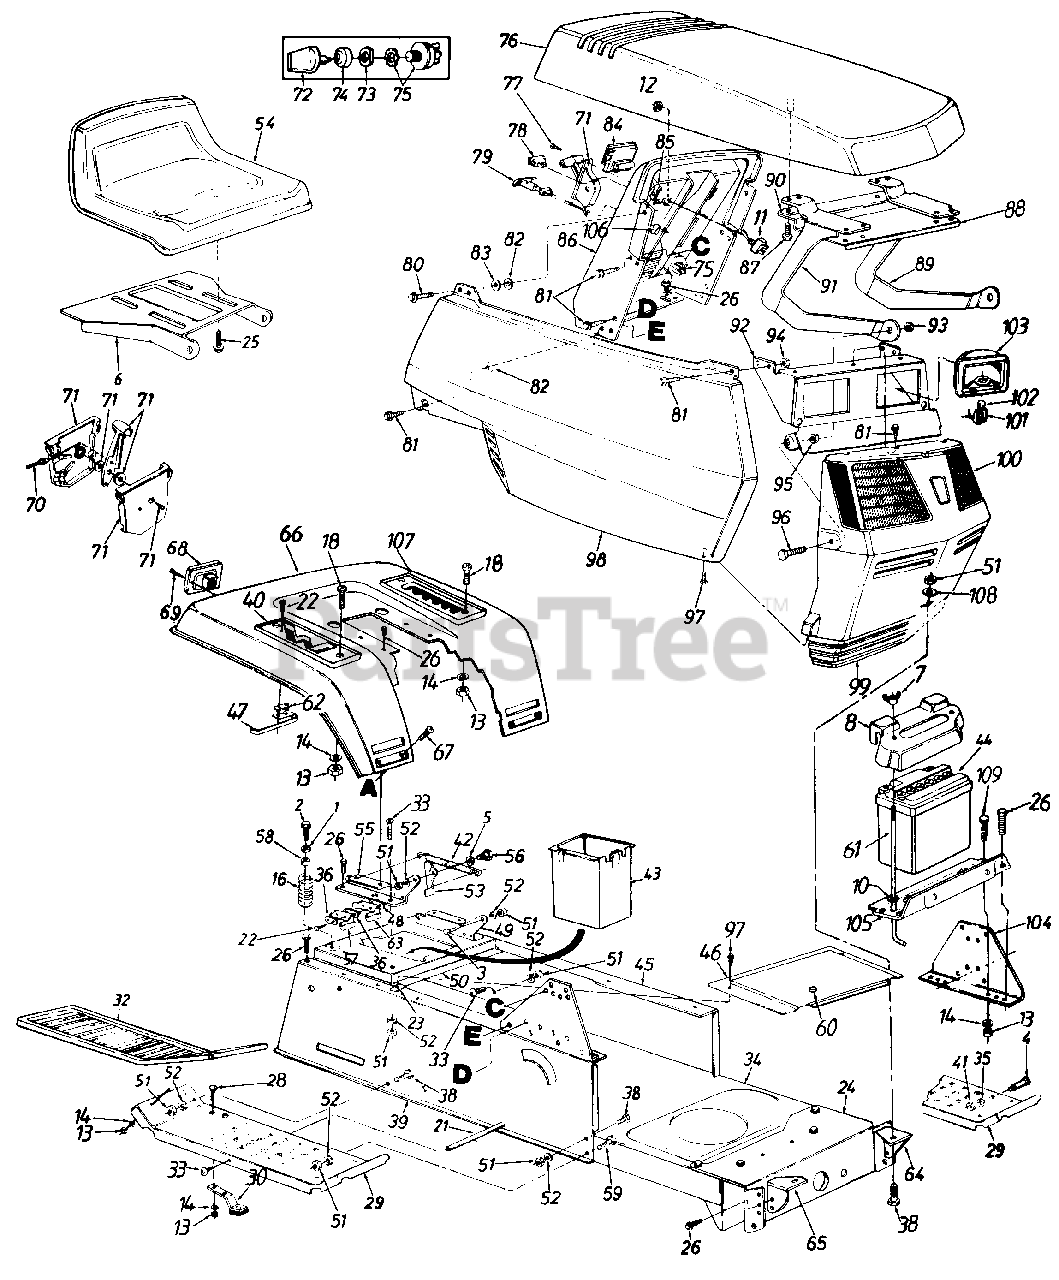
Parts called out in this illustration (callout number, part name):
1	Fl-Wash. .344" I.D. x .875"
2	Hex Wash. Hd. Tap Scr. 5/16-18 x 1.25" Lg.
3	Shld. Bolt .437" Dia. x .162"
4	Shld. Bolt .50" Dia. x .84"
5	Spr-Wash. .445" I.D. x .75
6	Seat Pivot Bracket
7	Wing Nut 1/4-20 Thd.
8	Battery Cover
10	Push Nut
11	Toggle Switch
12	Hex Nut l/2-27 Thd.
13	Hex Nut 1/4-20 Thd.
14	L-Wash. 1/4" I.D.
16	Compression Spring
18	Truss Mach. Scr. 1/4-20 x .75" Lg.
21	Running Board Rod
22	Hex Wash. Hd. AB-Tap Scr. #8 x .50" Lg.
23	Speed Nut #10Z
24	Front Pivot Brkt.
25	Hex Tap Scr. 3/8-16 x .75"
26	Hex Wash. Hd. AB-Tap Scr. 5/16 x .75" Lg.
28	Carriage Bolt 1/4-20 x .62"
29	Running Board
30	Blade Brake Ass'y.
32	Rubber Foot Pad L.H.
33	Truss Mach. Scr. 5/16-18 x .75" Lg.
34	Lower Frame
35	L-Wash. 3/8" I.D.
36	Insulator Plate
38	Hex Bolt 5/16-18 x .75" Lg.
39	Upper Frame R.H.
40	Forward/Reverse Index Brkt.
41	Hex Nut 3/8-16 Thd.
42	Extension Spring 5.31" Lg.
43	Utility Box
44	12-V Battery (275 Cold Crank Amps)
45	Upper Frame L.H.
46	Shift Cover
47	Reverse Safety Switch
48	Insulator Boss Plate
51	Hex Nut 5/16-18 Thd.
52	L-Wash. 5/16" I.D.
53	Seat Lift Brkt.
54	Seat
57	Spring Switch
58	Bushing
59	Part Specification Not Listed
60	Snap Bushing
61	Battery Hold Down Rod
62	Insulator,Nut Plate
63	Safety Switch (Seat)
64	Grille Mount Brkt. L.H.
65	Grille Mount Brkt. R.H.
66	Fender
67	Carriage Bolt 1/4-20 x .62" Lg.
68	Taillight
69	Truss Hd. AB-Tap Scr. #6 x .62" Lg.
70	Throttle Wire 35" Lg.
71	Throttle Control Box Ass'y.
72	Ignition Key
73	Ignition Switch Nut
74	Ignition Switch Cap
75	Ignition Switch
78	Light Switch
79	Choke Control 38" Lg.
80	Hex Wash. Hd. Tap Scr. 1/4 x .75" Lg.
81	Hex Tap Scr. 1/4-20 x .5" Lg.
82	Push Nut Fastener
83	Fl-Wash. .27" I.D. x .948"
84	Ammeter
85	Speed Nut 1/4-20 Thd.
86	Dash Panel
87	Hex Wash. Hd. B-Tap Scr. 1/4 x .62" Lg.
88	Hood Reinforcement
89	Hood Hinge L.H.
94	Hex L-Nut 1/4-20 Thd.
95	Hex Jam Nut 5/16-18 Thd.
96	Hex Bolt 5/16-18 x 7/8" Lg.
97	Truss Mach. B-Tap Scr. #10 x .5" Lg.
98	Side Cover R.H.
99	Grille
100	Lens L.H.
101	Twist Lock Lamp Socket
102	Lamp
103	Headlight Housing
104	Dash Support Brkt.
105	Support Brkt.
106	Choke Retainer
107	7-Speed Index Brkt.
108	Fl-Wash. .34" I.D. x .68" O.D.
109	Hex Bolt 1/4-20 x .62" Lg.
